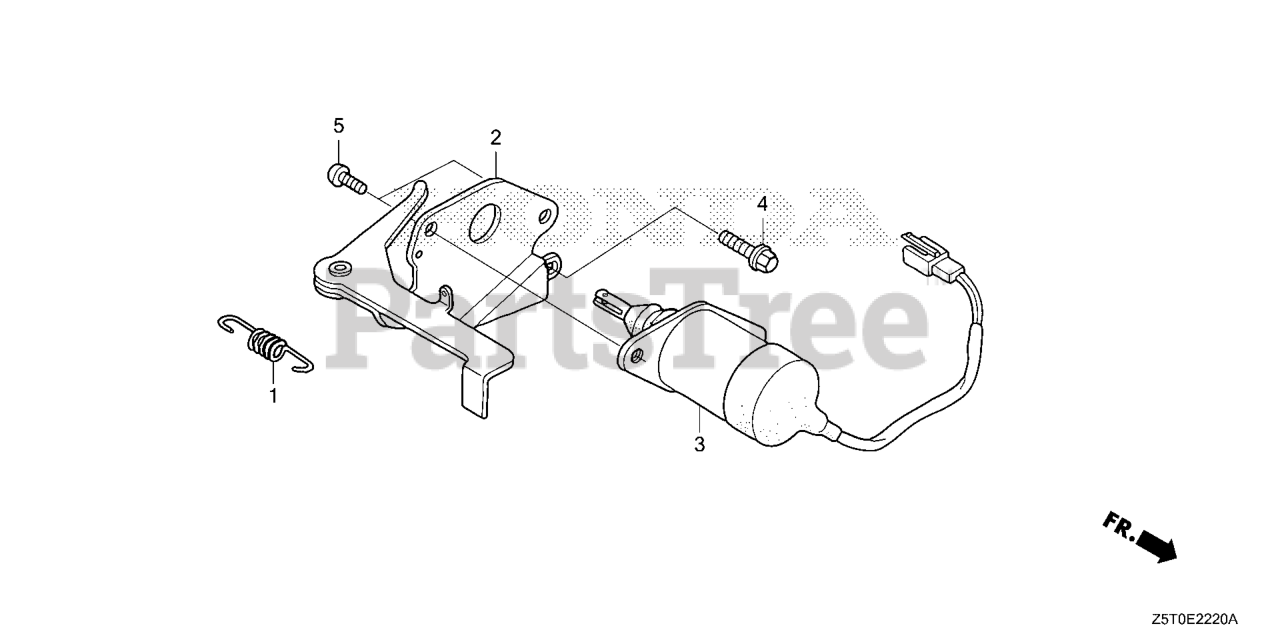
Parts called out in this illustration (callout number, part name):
1	SPRING, CHOKE RETURN
2	LEVER, THROTTLE
3	SOLENOID ASSY.
4	BOLT, FLANGE (6X12) (CT200)
5	SCREW, PAN (5X8)
